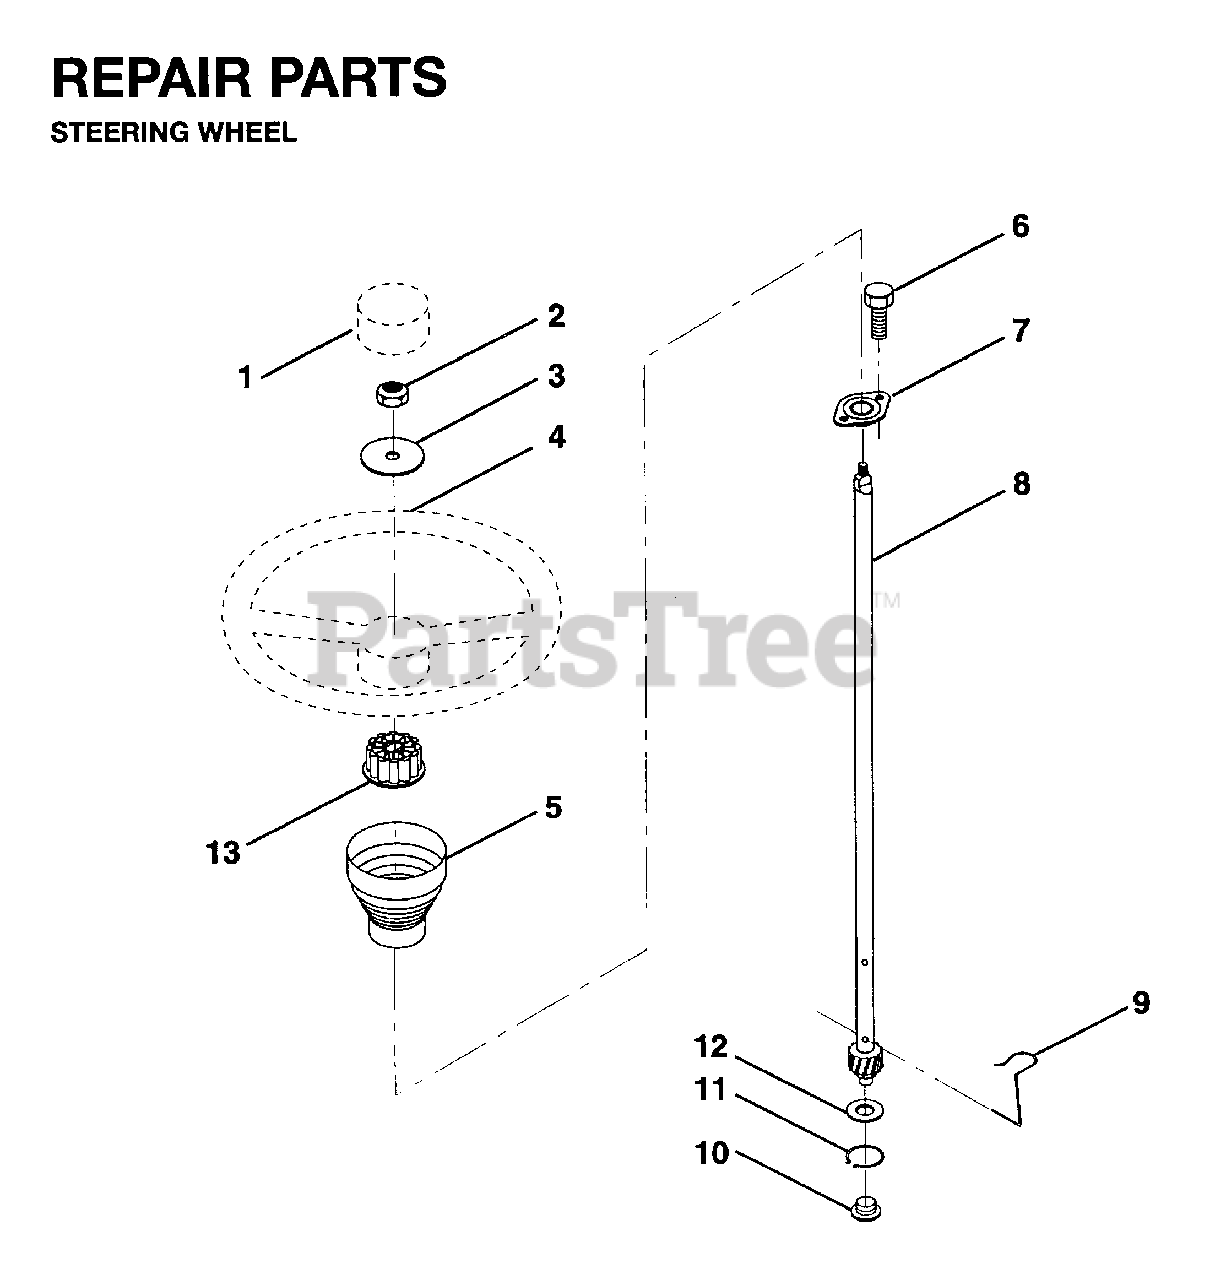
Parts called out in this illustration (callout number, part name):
2	NUT
3	WASHER T
7	BUSHING-STRG LT
8	SHAFT STEERING
9	STEERING CLIP
10	BUSHING STEER LWR
13	ADAPTER-WHEEL LT
